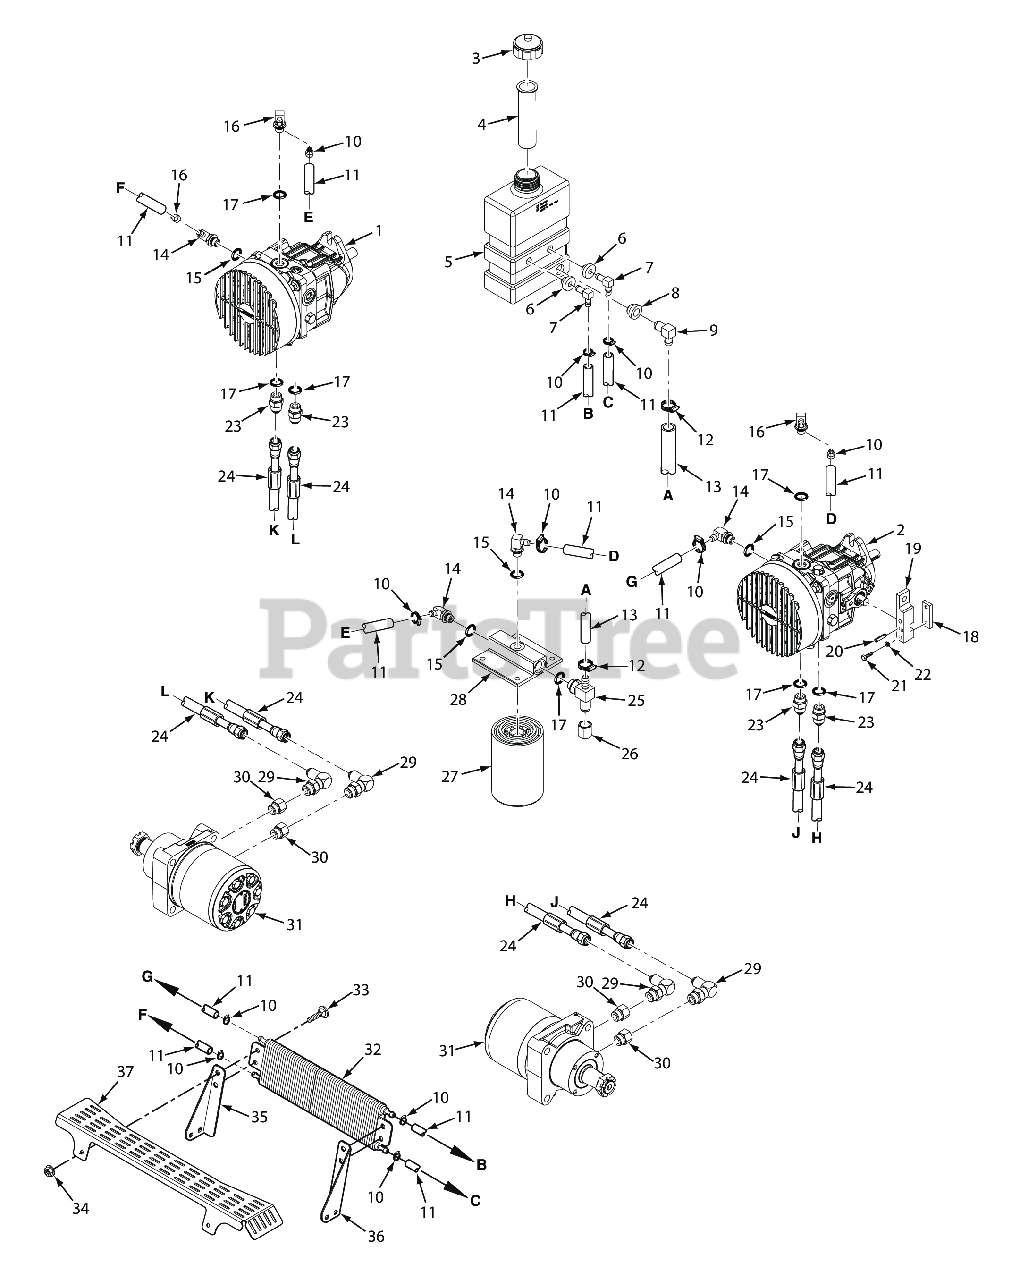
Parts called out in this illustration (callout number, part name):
1	Pump w/Fan, Right Hand (791DFI,35BVAC)
1	Pump, RH w/Fan (26EFI Only)
2	Pump w/Fan, Left Hand (791DFI, 35BVAC)
3	CAP, HYDRAULIC TANK
4	Insert, Filler Neck
5	Hydraulic Tank Assy., STTII
6	Bushing, 0.56" Dia. Viton
7	Elbow, 90 Degree, 9/16-18 JIC x 9/16 O-Ring
8	Bushing, 0.78" Dia. Viton
9	Fitting, 90 Degree - 1/2" Hose
10	Clamp, .69" Max. / .25" Min. Dia.
11	Hose, 3/8" ID - 10-1/4" Long (Order By The Inch)
12	Clamp, Cable 3/4" I.D.
13	Hose Assembly, 1/2" ID (Oil Reservoir to Filter Base)
14	Elbow, 90 Degree - 9/16" O-Ring x 3/8" Hose
15	"O" RING, 5/64 X 15/32 ID
16	Elbow, 90 Degree - 3/4" O-Ring x 3/8" Hose
17	"O" RING, 3/32 X 5/8" ID
18	Clamp Plate, Pump Control
19	Block, RH Pump Control
19	Block, LH Pump Control
20	Roll Pin, Spring 3/16 x 3/4"
21	Bolt, Hex Head, 1/4-20 x 1-1/2"
22	Lockwasher, 1/4� Spring
23	Fitting, Union 3/4-16 JIC X O-Ring
24	Hose Assembly
25	Tee, 3/8" O-Ring x JIC x 1/2" Hose
26	CAP, 3-4-16 JIC
27	FILTER, SPIN-ON LUBE
28	Filter Head Assembly
29	ELBOW, 90DEG, 7/8-14 JIC X 7/8-14 O-RING
30	Bushing, 7/8"-14 JIC x 3/4"-16 O-Ring
31	Wheel Motor, Parker TG - 18ci.
32	Cooler, Transmission
33	Serr. Fl. Hex Head CPSCR, 1/4-20 x 3/4"
34	NUT, 1/4-20 SERRATED FLANGE HEX HEAD
35	Mounting Bracket - RH, Oil Cooler
36	Mounting Bracket - LH, Oil Cooler
37	Screen Guard, Kohler EFI
37	Screen Guard, Briggs & Stratton 35BV
37	Screen Guard, Briggs & Stratton 37BV-EFI
